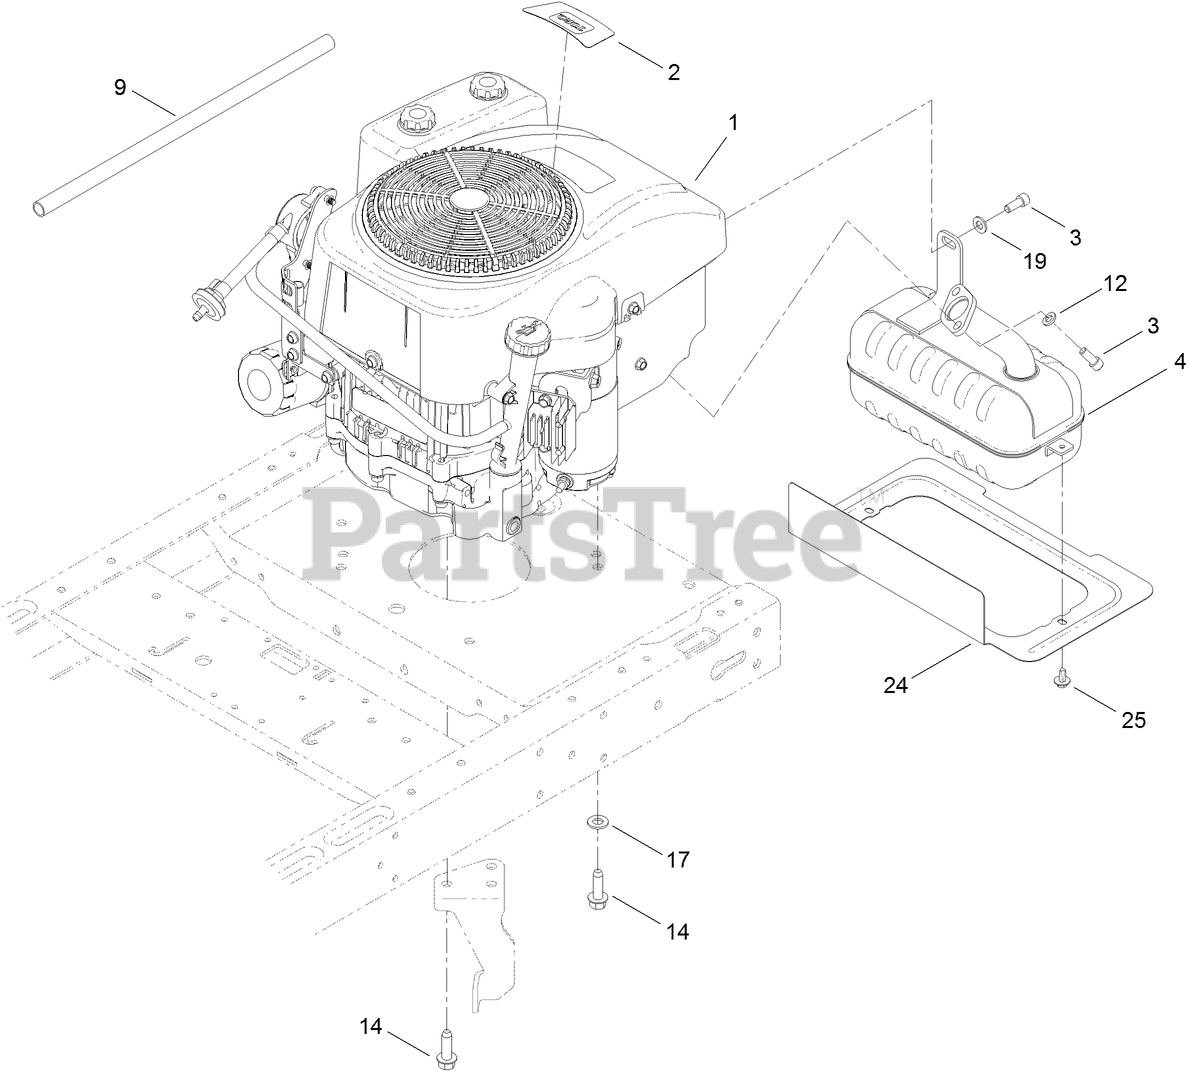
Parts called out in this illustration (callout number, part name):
2	DECAL-ENGINE, TORO
3	SCREW-HSH
9	TUBE-DRAIN, OIL
12	WASHER-LOCK
14	SCREW-THD
17	WASHER-FLAT
19	WASHER-PLAIN
24	SHIELD-HEAT
25	SCREW-HHFTF
